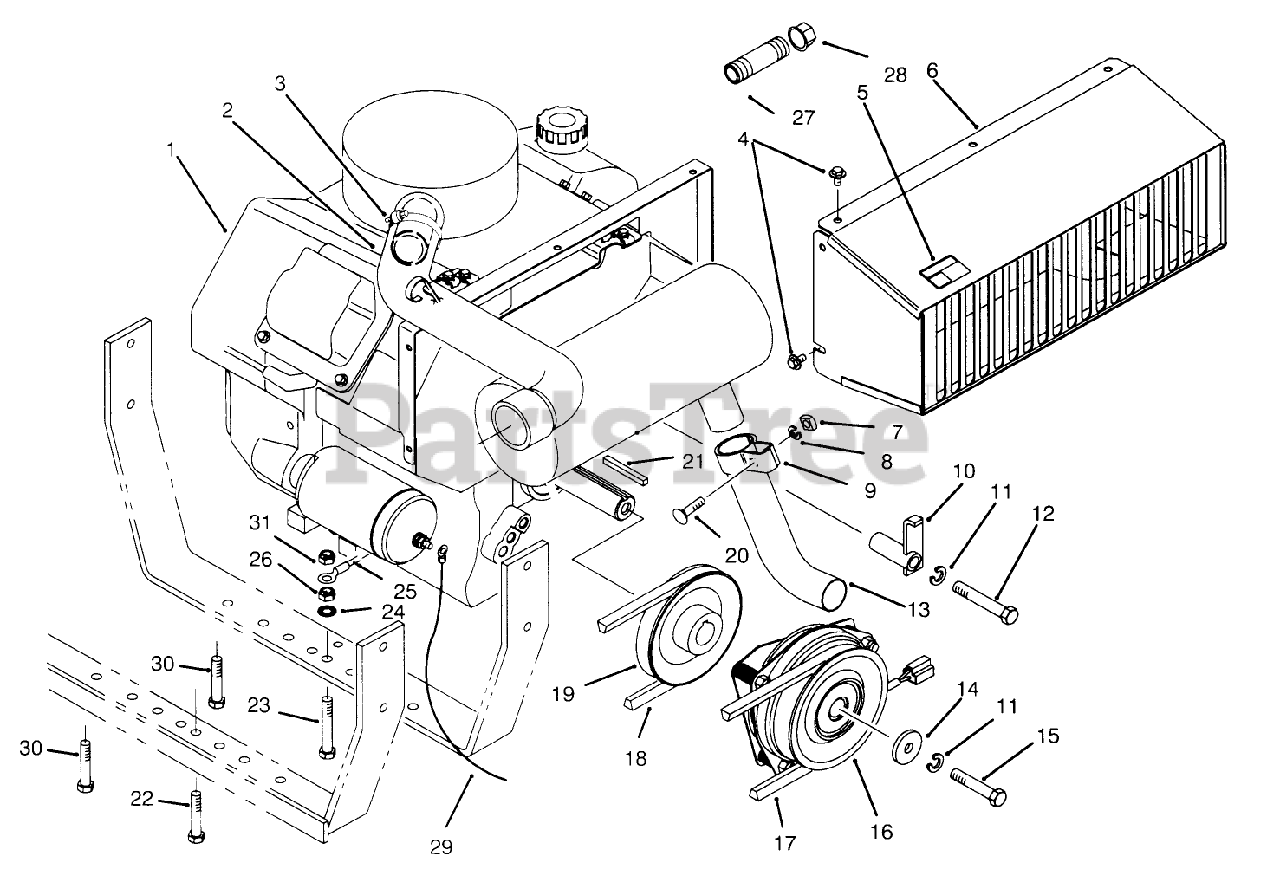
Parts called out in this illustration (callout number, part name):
2	CARB INTAKE HOSE
3	CLAMP-HOSE
4	SCREW
5	DECAL-SURFACE, HOT
6	Duct-Engine
7	NUT-HEX
8	WASHER-LOCK
9	Assembly-Clamp (Incl. Ref. #7, 8 & 20)
10	Anchor Bracket
11	WASHER-LOCK
12	SCREW-HH
13	EXHAUST PIPE
14	WASHER-CLUTCH
15	SCREW-HH
16	BRAKE CLUTCH ASM
17	V-BELT, JACKSHAFT
18	V-BELT, TRACTION
19	ENGINE PULLEY
20	SCREW-CARR
22	SCREW-HH
23	SCREW-HH
24	WASHER-LOCK, INTERNAL
25	WIRE ASM (NEGATIVE)
26	NUT-LOCK, NI
27	NIPPLE-PIPE
28	CAP-PIPE
29	POSITIVE WIRE ASM
30	SCREW-HH
31	NUT-HHF, WHIZ
